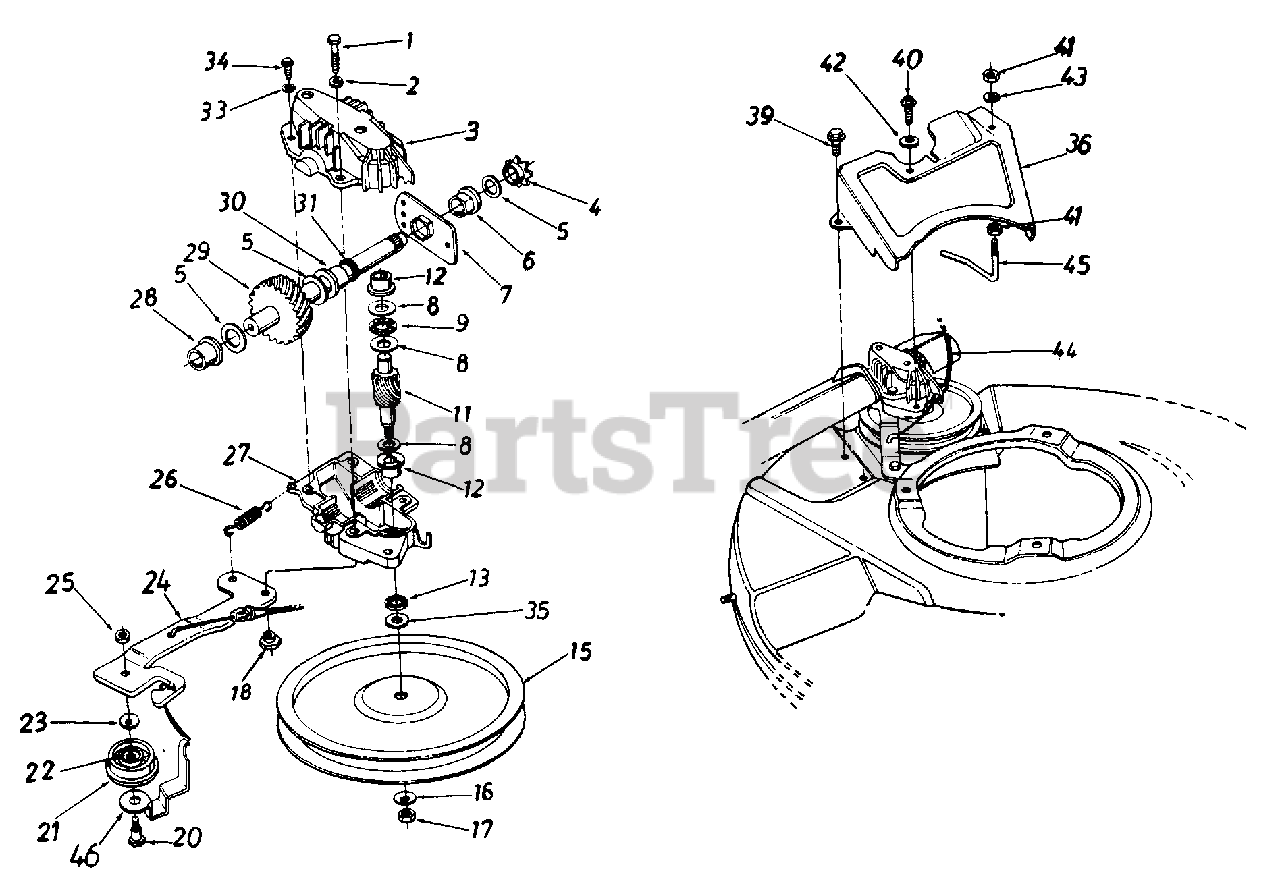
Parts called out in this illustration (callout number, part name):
1	Hex Bolt w/Patch 1/4-20 x 1.25"
2	L-Wash. 1/4" I.D.
3	Upper Hsg. Half
4	#48 Sprocket 7 Tooth x 1/2 Pitch
5	Fl-Wash. 5/8" I.D. x 030
6	Hex Flange Brg. .631" I.D.
8	Thrust Wash. .382" I.D. x .70" O.D.
9	Thrust Bearing .375" I.D. x .812" O.D.
11	11 Tooth Helical Gear
12	Flange Bearing
13	Oil Seal
15	Fl-Pulley 5.05" I.D.
16	Bell-Wash. .265" I.D. x .75"
17	Hex Nut 1/4-28 L.H. Thd.
18	Shld. Spacer .375" Dia. x .170
20	Shld. Bolt. 375" Dia. x .40"
21	Fl-Idler Plastic 1.50" Dia.
22	Needle Brg. .375" x .31"
23	Bell-Wash. .265" I.D. x .75"
24	Idler Brk't. Ass'y.
25	Hex Patch L-Nut 1/4-28 Thd.
26	Extension Spring 1.12" Lg.
27	Lower Hsg. Half
28	Flange Bearing .56 Dia.
29	33 Tooth Helical Gear
30	Flange Bearing .629 Dia.
31	Oil Seal .625 Dia.
33	L-Wash. #10 I.D.
34	Hex B-Tap Scr. #10 x .62"
35	Hex Washer. 26" x .88"
40	Hex B-Tap Scr. 1/4 x .62" Lg.
41	Hex Nut 1/4-20 Thd.
42	Bell-Wash. .265" I.D. x .75"
43	L-Wash. 1/4" I.D.
44	S.P. Cable - 48" Lg.
45	S.P. Belt Guard
46	Belt Keeper
